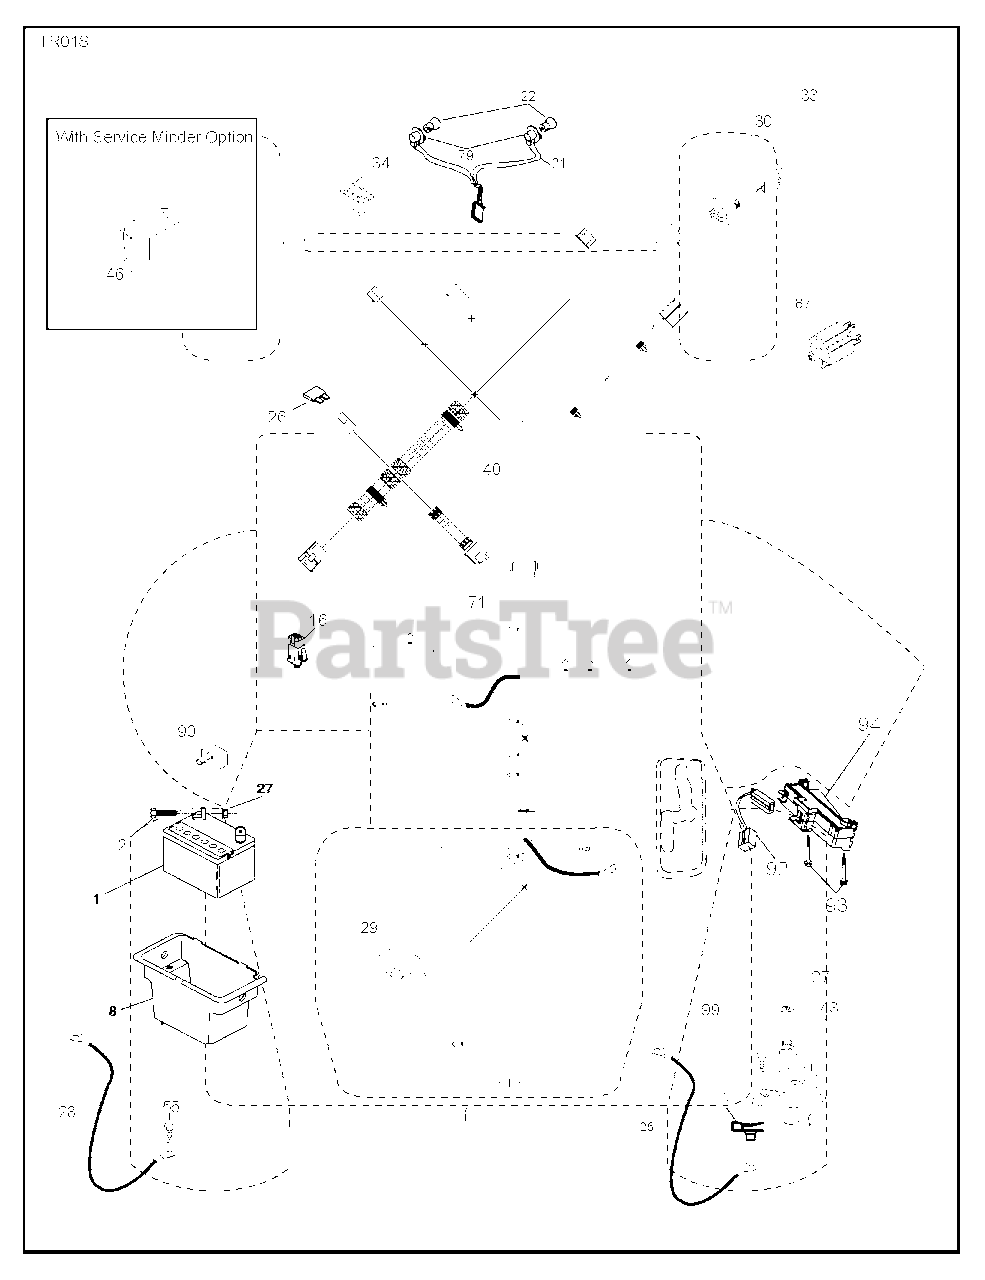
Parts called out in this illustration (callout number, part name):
1	Battery, Dry 30 Amp
2	BOLT.HEX.1/4.X.3/4.DICHROMATE
8	BOX.BATTERY.MNT.REAR.L
16	SWITCH INTERLOOK PUSH-IN
21	HARNESS.LIGHT W/4152J BULBS
25	CABLE.BATT.RED.8GA.17
26	FUSE 20AMP
27	NUT
28	CABLE.GROUND.REAR.BATTERY.8G
29	SWITCH.SEAT.DELTA.OPC.
30	SWITCH.IGN.DELTA.W.LGH.ROS
33	KEY.CHAIN.BLISTER.PACK.GEN.USA
40	HARNESS.TEX.DASH.MAN.REAR BATT
43	SOLENOID.W/BRASS.PLUNGER
55	SCREW 5/16"
71	HARNESS.TEX.CHSSIS.REAR.BATT
79	BULB HOLDER ASM.
87	SWITCH.INTRLCK.CLUTCH.
90	COVER.TERMINAL.BATTERY
92	HARNESS.PIGTAIL.CONSLE
93	SCREW.PLASTITE
94	MODULE.REVERSE.ROS
99	SCREW HEXWSHR 1/4-20X3/4
106	1/4-20 U NUT
